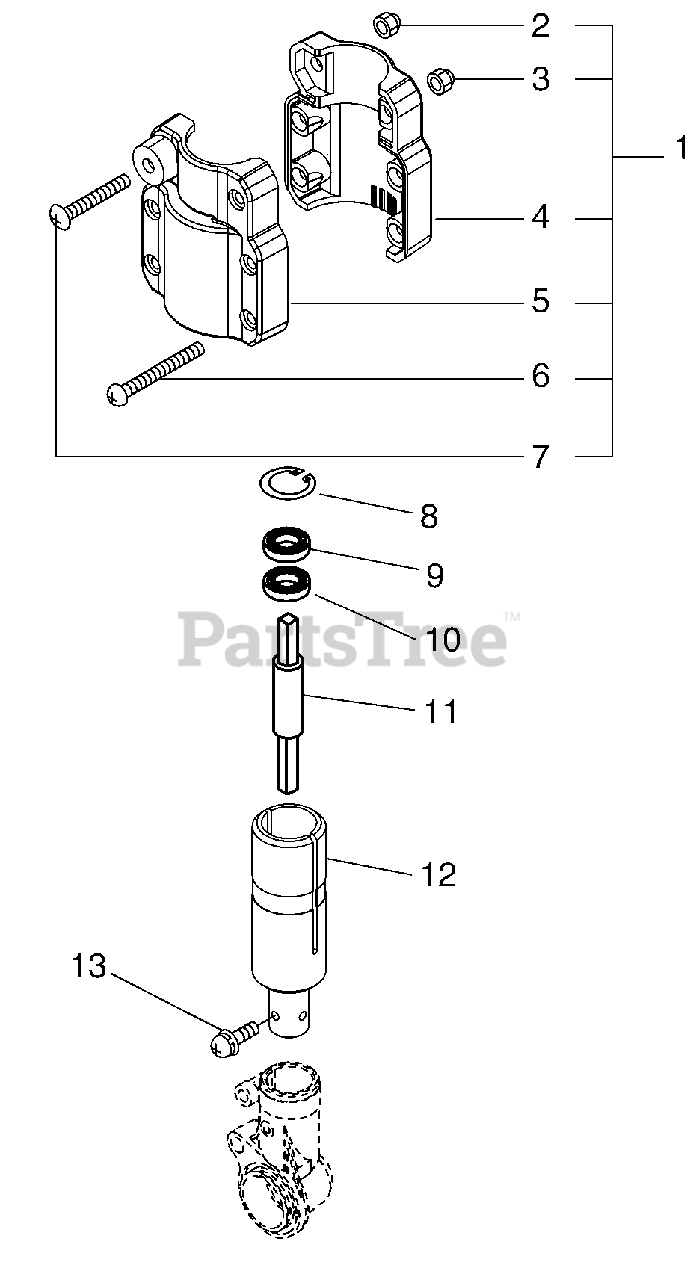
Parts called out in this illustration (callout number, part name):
1	COLLAR, MAIN PIPE
2	NUT, LOCK
3	NUT, LOCK 10-24 UNC
4	COLLAR, LOWER
5	COLLAR, UPPER
6	SCREW, TORX 10-24 UNC 1-1/4
8	RING, SNAP Ø32
9	BEARING, BALL 6201
10	BEARING, BALL 6201
11	CONNECTOR, SHAFT
12	COUPLING
13	SCREW 5×10
